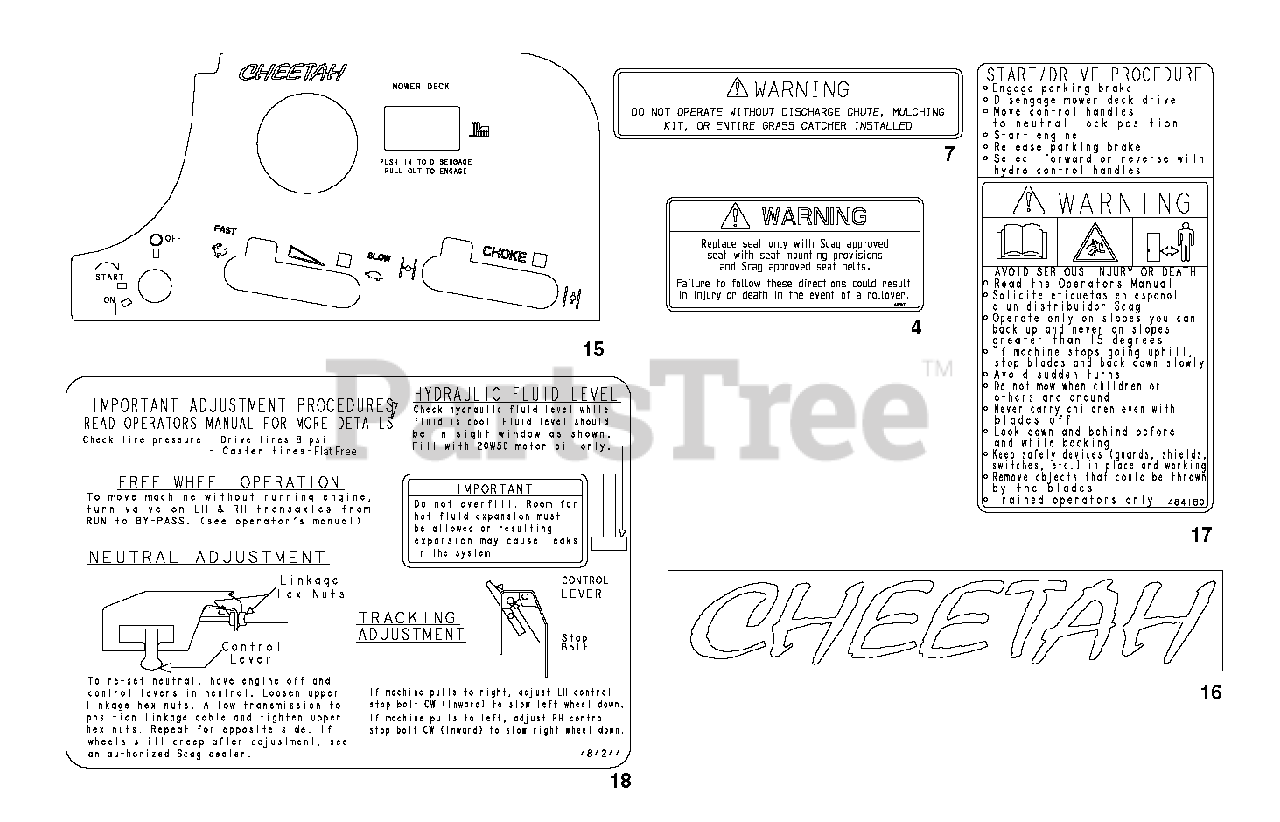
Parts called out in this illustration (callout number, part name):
4	Decal, Seat Replacement
7	Decal, Warning
15	Decal, Instrument Panel - SCZ
16	Decal, Cheetah
17	Decal, Start / Drive
18	Decal, Adjustments - SCZ
